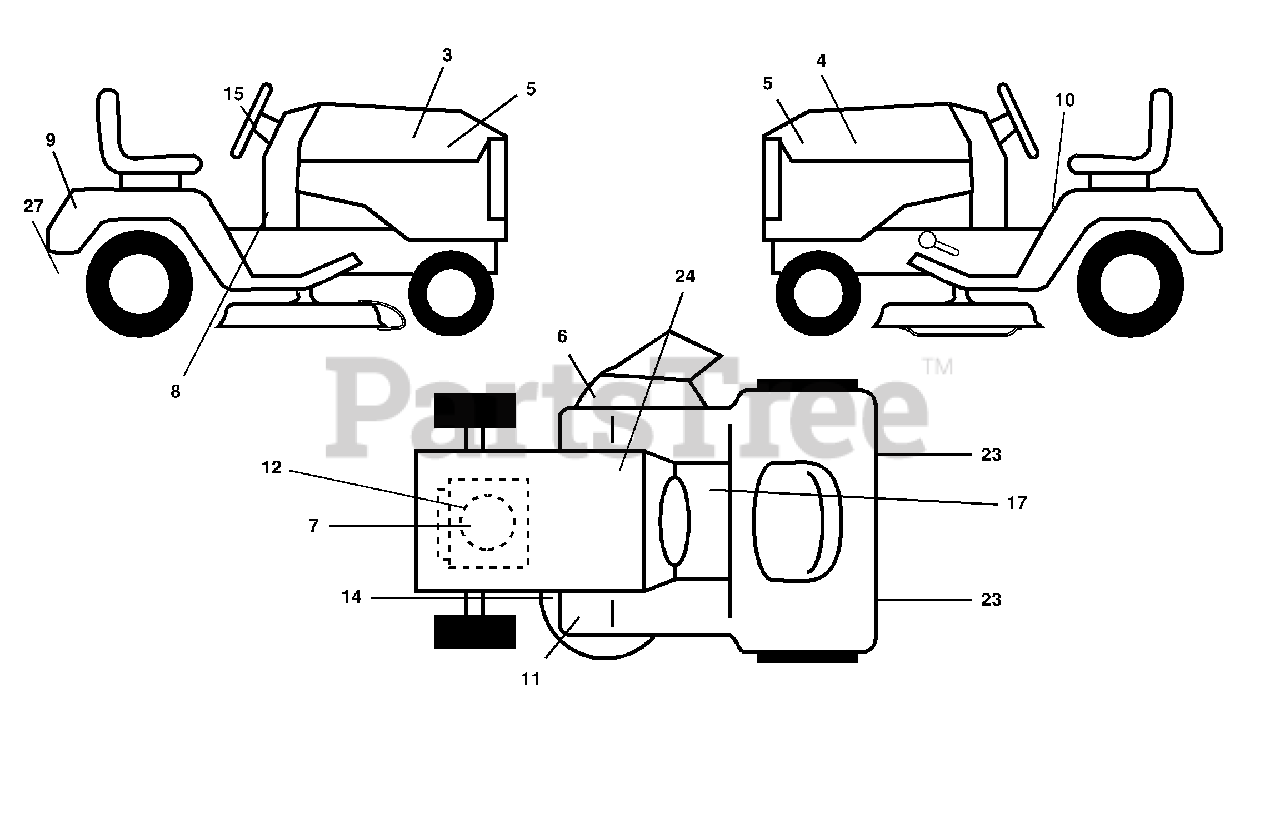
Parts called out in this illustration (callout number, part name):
3	Decal, Hood, RH
4	Decal, Hood, LH
5	Decal, Side Panel
6	Decal, Warning
7	Decal, Engine HP
8	Decal, Dash
9	Decal, Fender
10	Decal, Danger
11	Decal, Clutch/Brake
12	Decal, Engine RCL
14	Decal, V-Belt Schematic
15	Decal, Ins. Strg Whl
17	Decal, Saddle Brake Parking
23	Reflector, Taillight
24	Decal, Btry Dngr/Psn
27	Decal, Bypass
